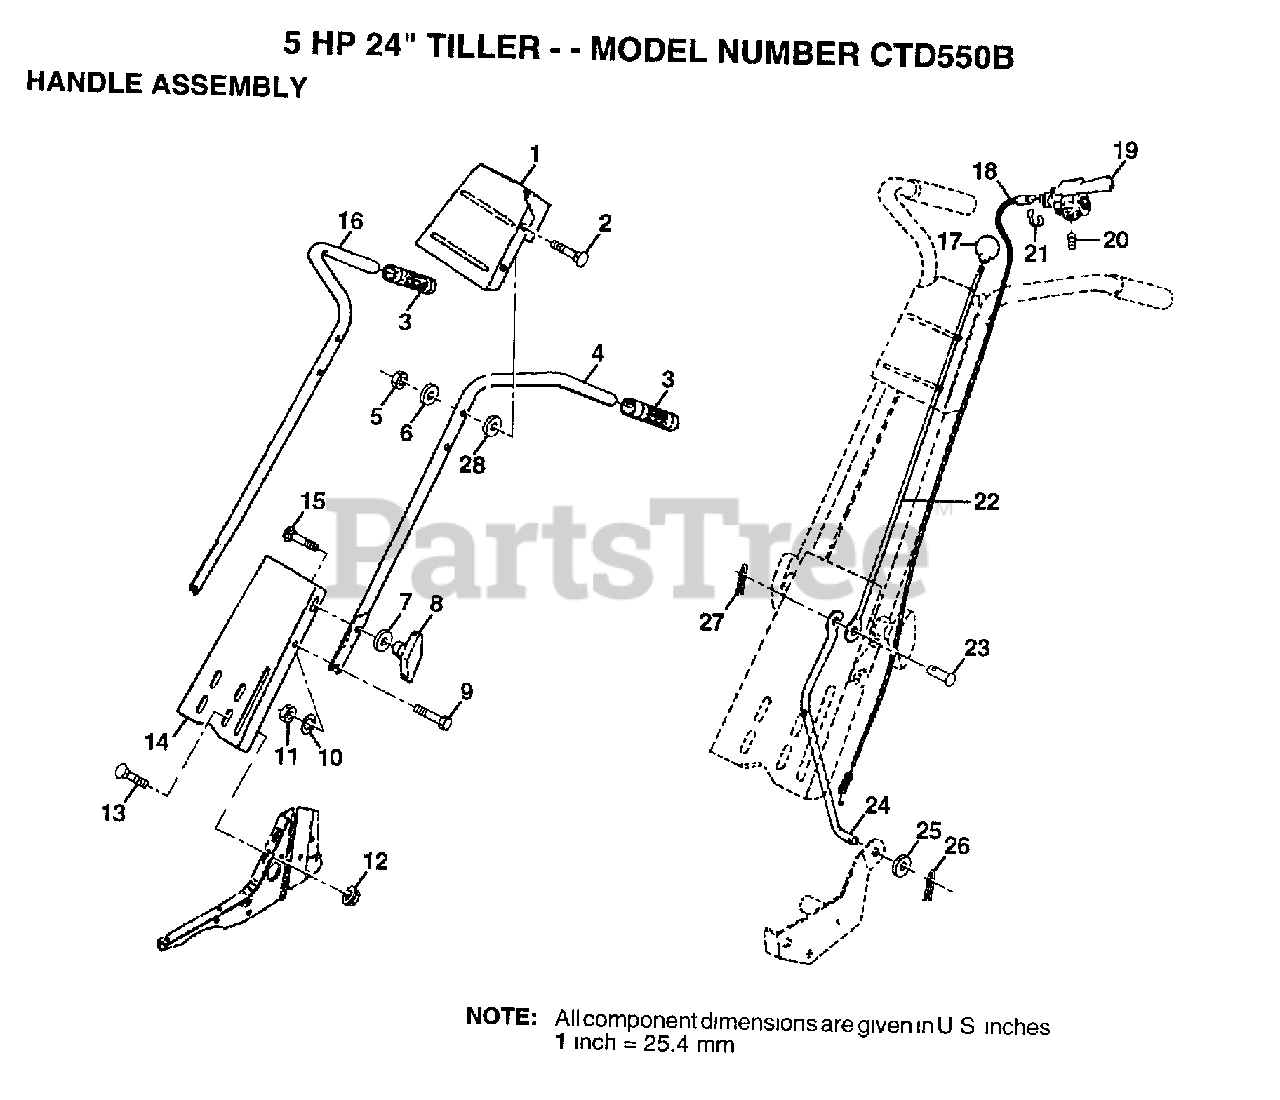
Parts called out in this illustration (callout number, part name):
1	HANDLE BRACKET
2	BOLT
3	GRIP NUB DOUBLE
4	HANDLE PNT LH
6	WASHER
7	WASHER
8	KNOB HANDLE
10	LOCKWASHER
11	NUT.HEX.5/16-18
12	NUT
13	BOLT
15	BOLT
16	HANDLE PNT RH
17	KNOB T(3/8 HOLE)
18	CABLE CLUTCH T
19	CONTROL LEVER TI
20	SCREW
21	E-RING
22	ROD REVERSE TI
23	RIVET.RD.HD.DRILL
24	REVERSE ROD TI
25	WASHER
26	COTTER PIN
28	WASHER
